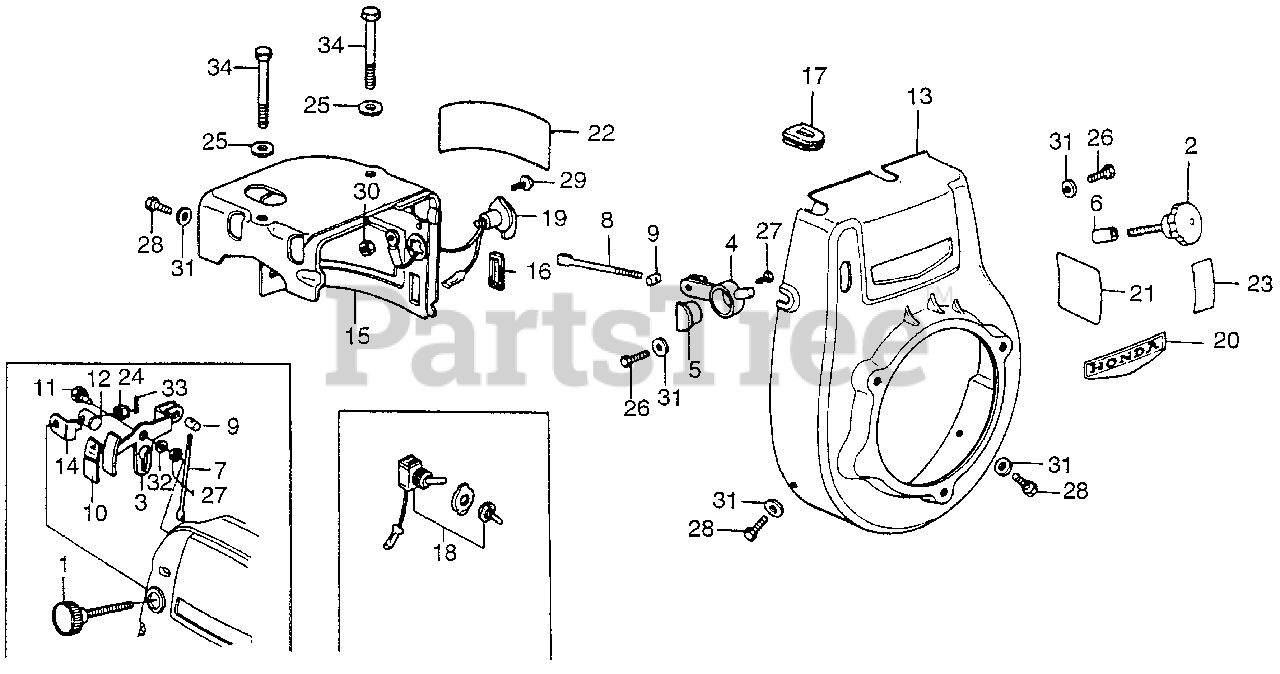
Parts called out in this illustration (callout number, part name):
2	SCREW, GOVERNOR ADJUST (NOT AVAILABLE)
4	LEVER, CONTROL (NOT AVAILABLE)
5	SHAFT, CONTROL
6	BUSH, CONTROL (NOT AVAILABLE)
8	ROD, ADJUSTING
9	JOINT, ADJUSTING ROD (NOT AVAILABLE)
13	COVER, FAN *R8* (BRIGHT RED) (NOT AVAILABLE)
15	COVER, SIDE *R8* (BRIGHT RED)
17	GROMMET, WIRE
19	SWITCH ASSY., ENGINE STOP
20	EMBLEM (NOT AVAILABLE)
22	PLATE, DESCRIPTION
23	PLATE, THROTTLE (ENGLISH/FRENCH)
25	WASHER, HEAD (8MM)
26	BOLT, HEX. (5X8)
28	BOLT, HEX. (6X12)
29	SCREW, PAN (5X8)
30	NUT, HEX. (5MM)
31	WASHER, PLAIN (6MM)
